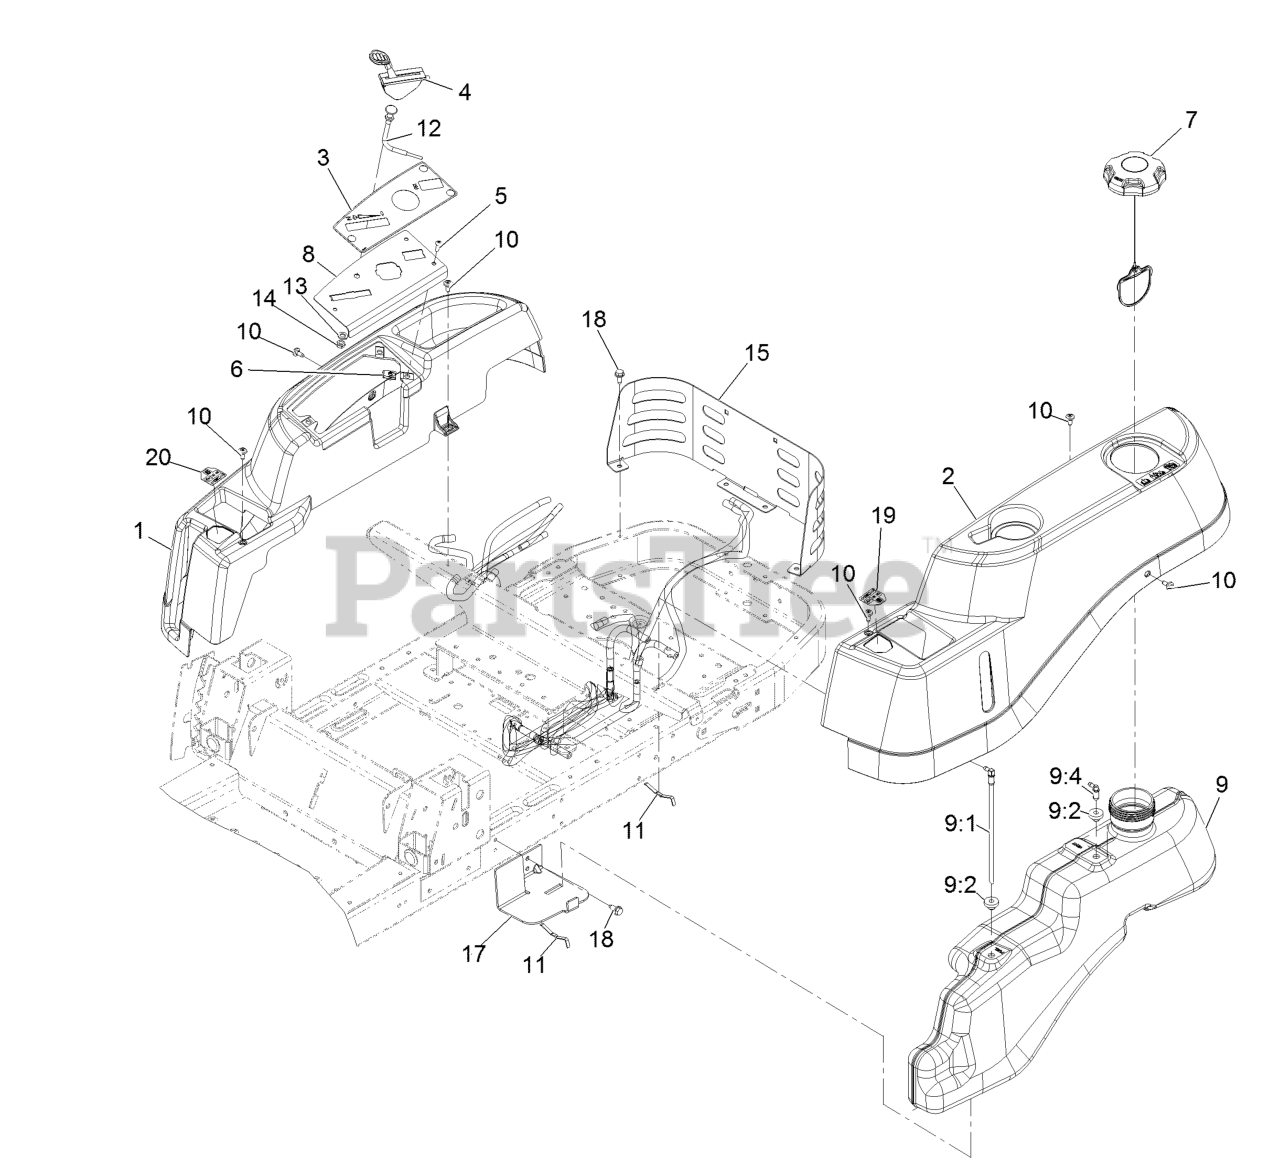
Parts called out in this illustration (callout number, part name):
3	DECAL-PANEL, CONTROL
4	CABLE-THROTTLE
5	SCREW-PRH
6	Nut-Retainer-Panel 1/4-20
8	PLATE-CONTROL
9	FUEL TANK ASM
9:1	CONNECTOR-ELBOW, 90 DEG
9:2	BUSHING
9:4	FITTING-PLASTIC
10	SCREW-SHOULDER
11	SPRING
12	CABLE-CHOKE
13	WASHER-LOCK
14	NUT-HJ
15	GUARD-REAR
17	SUPPORT-TANK, FRONT
18	Screw-HWH 5/16-18 X 3/4 Tf
19	DECAL-LEVER, CONTROL (LH)
20	DECAL-LEVER, CONTROL (RH)
